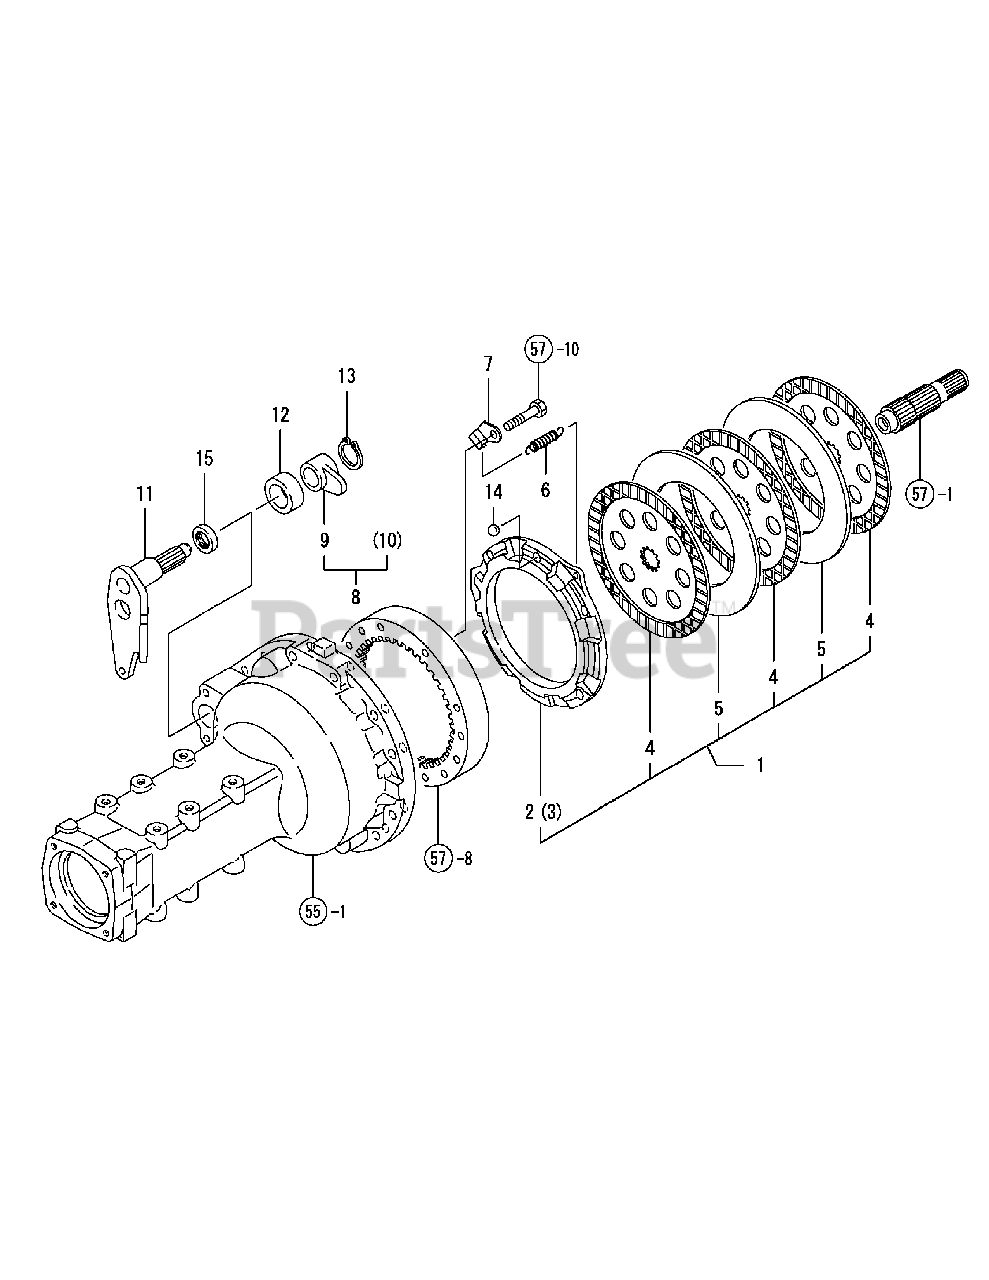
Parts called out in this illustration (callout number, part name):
4	PLATE 226, FRICTION
5	PLATE 3.2, STEEL
6	SPRING, ACTUATOR
7	HOOK, RETURN SPRING
8	LEVER COMPL.,CAM
9	CAMSHAFT, BRAKE
10	CAMSHAFT, BRAKE
11	SHAFT, CAM LEVER
12	SLEEVE, CAM LEVER
15	SEAL TC30 42 08, OIL
